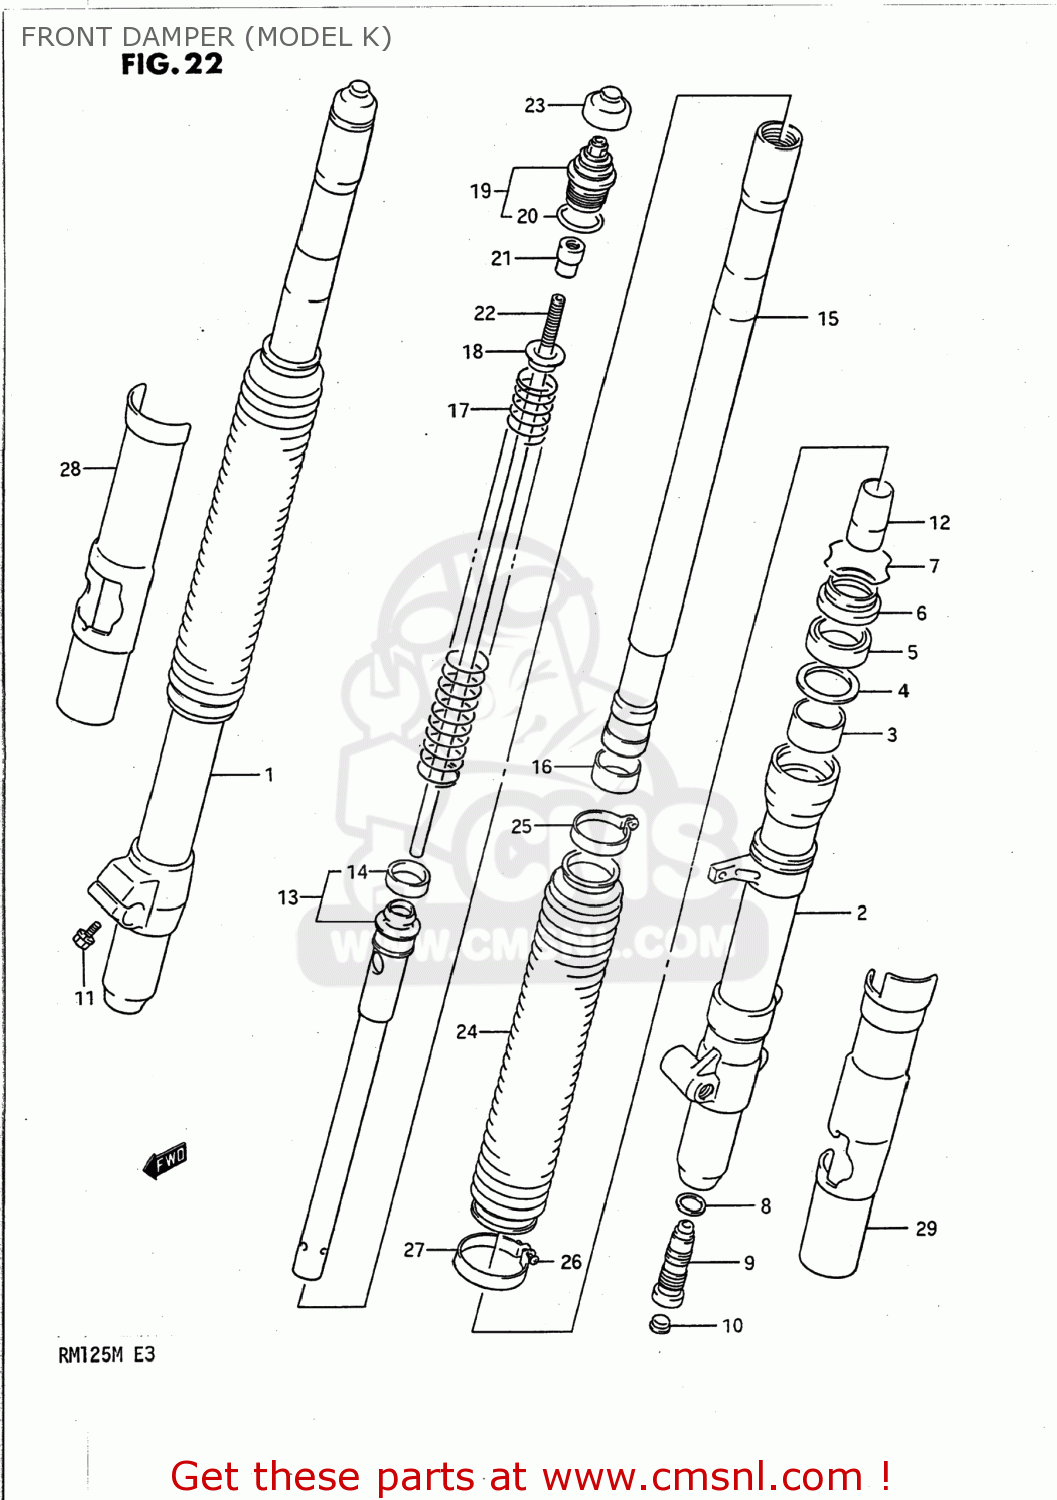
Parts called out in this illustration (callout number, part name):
1	TUBE,OUTER,RIGHT
2	TUBE,OUTER,LEFT
3	METAL,SLIDE
4	WASHER
5	OIL SEAL,FRONT FORK
6	DUST SEAL,FRONT FORK
7	RING,STOPPER
8	GASKET (NAS)
9	BOLT,CENTER
10	CAP,FRONT FORK DF
11	BOLT,RH
12	PIECE,OIL LOCK
13	CYLINDER
14	RING,SLIDE
15	TUBE,INNER
16	PISTON
17	SPRING
18	GUIDE,SPRING
19	CAP
20	O RING
21	NUT,PISTON ROD
22	ROD,PISTON
23	CAP
24	BOOT
25	BAND,BOOT,UPPER
26	SCREW,BAND BOOT(3.5X10)
27	BAND,BOOT,LOWER
28	PROTECTOR,RIGHT
29	PROTECTOR,LEFT
